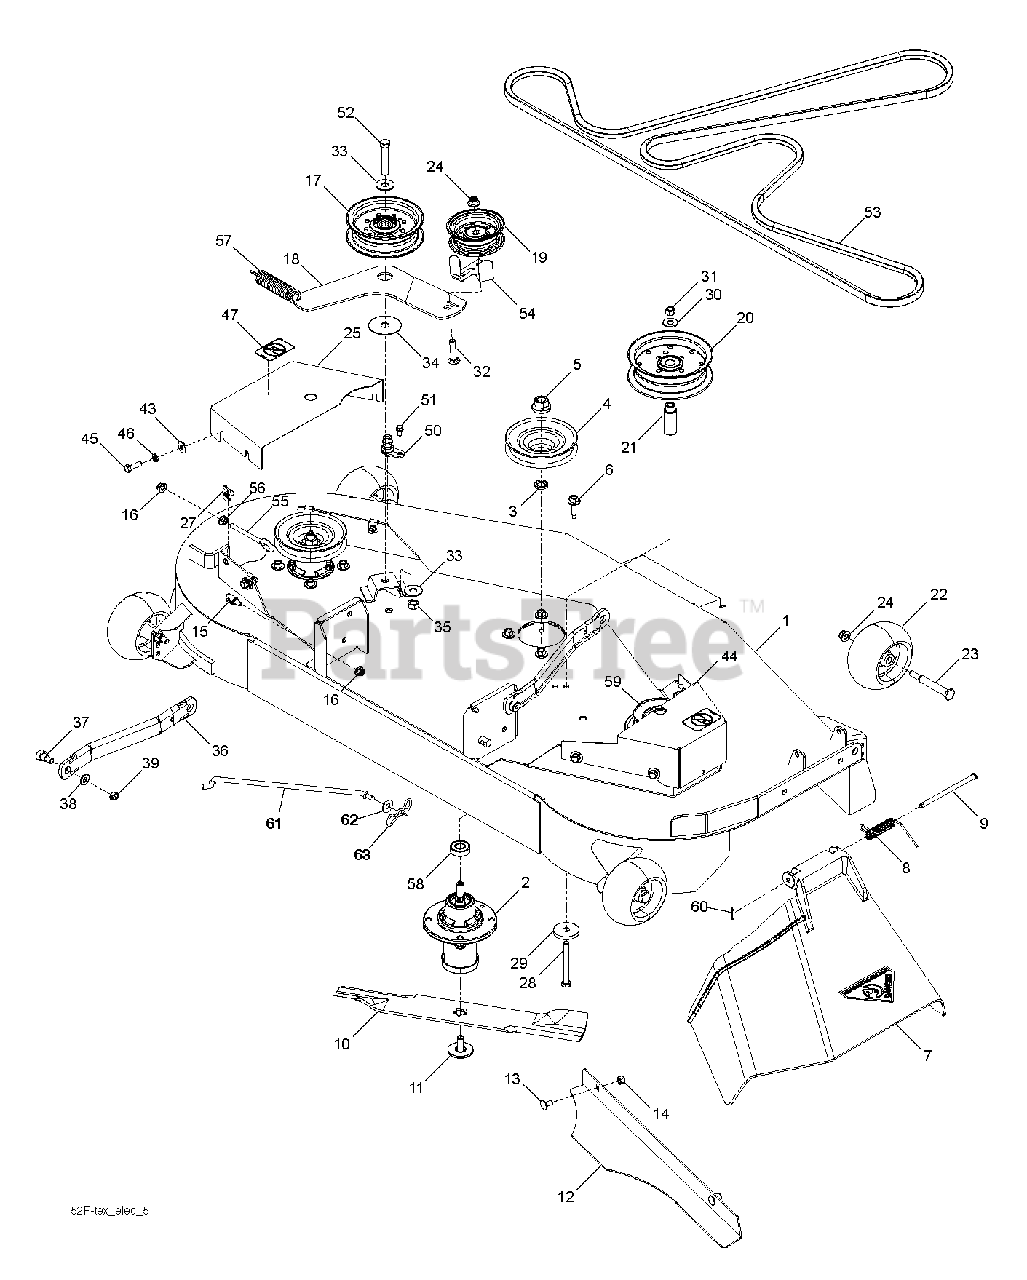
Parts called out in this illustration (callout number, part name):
1	DECK SVC W/DECALS.52.GTH.ORG
2	MANDREL.DECK.ASSEMBLY
3	WASHER.SPACER.MANDREL
4	RB PULLEY.IDLER.DRIVEN
5	NUT.FLANGE.LOCK.TOP
6	WASHER HEAD SCREW
7	DISCHARGE.CHUTE-52"
8	SPRING - TORSION
9	PIN, CLEVIS 5/16 X 5.19
10	BLADE, 17.75 X 2.5 X .25
11	BLADE BOLT ASSY-7/16" TB REPL
12	PLATE.52".CONFINEMENT.BLACK
13	CARRIAGE BOLT 5/16C X 5/8"
14	NUT 5/16 NYLOC
15	STUD.FASTNER.W/ANTI-ROTATE
16	5/16-18 NYLOC FLANGE NUT
17	PULLEY.IDLER.MWR.STATI.LH
18	ARM, IDLER, 52" BLK
19	PULLEY.IDLER.FLAT
20	PULLEY, IDLER
21	BUSHING, IDLER
22	GAUGE WHEEL
23	BOLT.SHOULDER.3/8-16X3-5/8.
24	NUT 3/8-16 HEX FLG NYLOC ZD
25	SHIELD.BELT.LH.ORANGE
27	U-CLIP 5/16-18 NUT RETAINER
28	HCS 3/8-16 X 3-1/2 GR5 ZD
29	SPINDLE WASHER
30	RP WASHER 3/8 FLAT
31	NUT 3/8-16 NYLOC
32	RHSNB 3/8-16X1-3/4
33	WASHER 7/16 FLAT ZD
35	7/16-14 HEX NUT W/NYL RING ZD
36	ARM.SUSPENSION.MOWER
37	SB 3/8-16 X 3/8 SKT HD ZD
38	WASHER 3/8 SAE FLAT
39	NUT HEX 3/8-16 NYLON, THIN
43	WASHER 5/16 FLAT
44	SHIELD BELT RH 52
45	HCS 5/16C X 1
46	WASHER 5/16 LOCK
47	DECAL, NO STEP
50	PORT.WASHOUT
51	BOLT 1/4-20 X 1/2 HWST
52	BOLT 7/16-14 X 2-1/2 GR 5 ZD
53	BELT, 143.5" EL
54	BELT GAURD
55	EYE BOLT 5/16 X 3.50
56	NUT 5/16C WHIZ
58	BEARING, BALL
59	RP PULLEY, COLLECTION 48
60	RETAINER CLIP
61	ROD.ANTI.SWAY.48/54"K4
62	WASHER
63	PIN.COTTER.5/16.BOW TI
